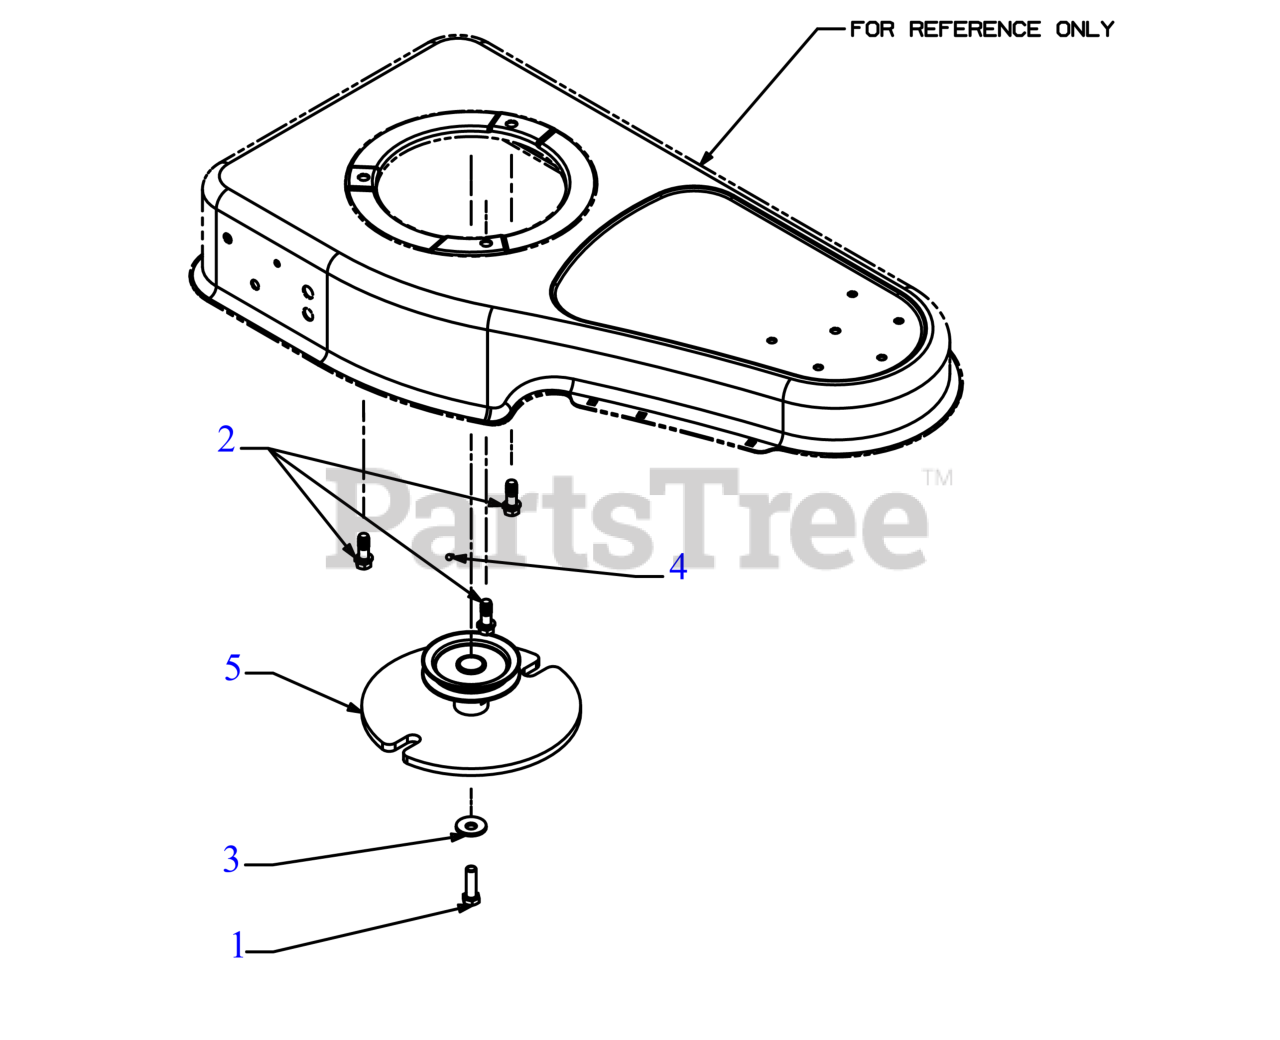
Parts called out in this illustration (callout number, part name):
1	SCREW 3/8-24X1.25
2	SCREW 3/8-16 x 1
3	BELL WASHER
4	NOT SERVICEABLE
5	PULLEY ASSEMBLY
